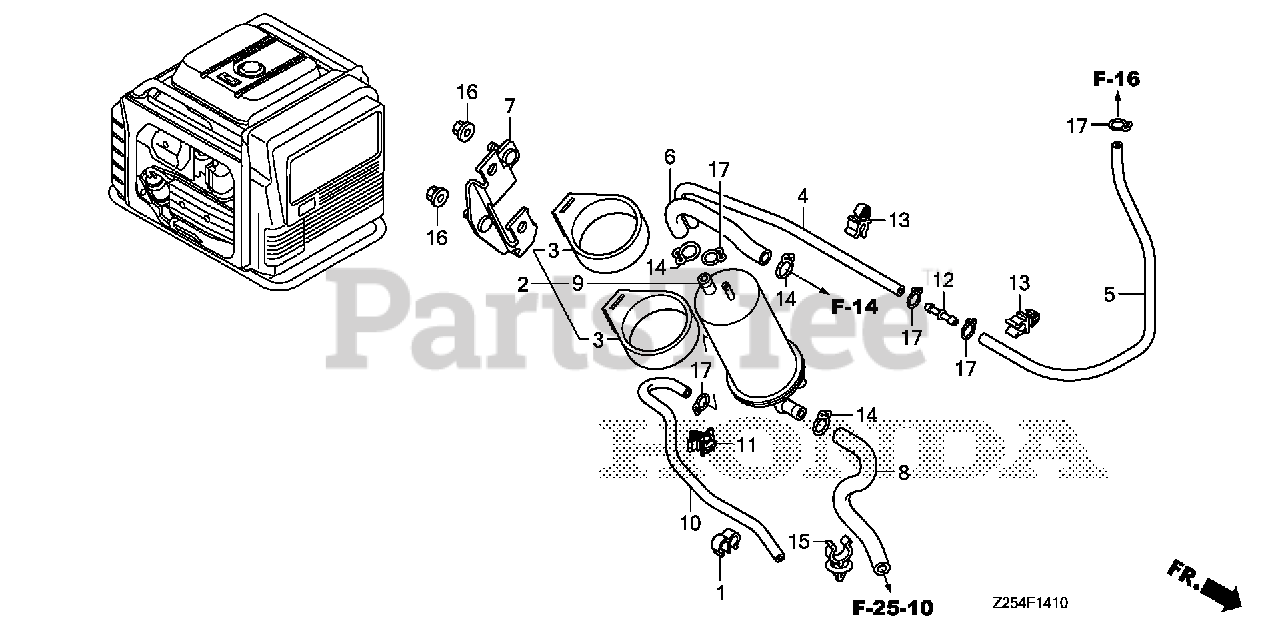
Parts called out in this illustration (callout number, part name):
1	CLAMP, TUBE (7.5X2)
2	CANISTER ASSY.
3	RUBBER, CANISTER MOUNTING
4	TUBE A, CANISTER CHARGE
5	TUBE, CANISTER CHARGE
6	TUBE, CANISTER PURGE
7	STAY, CANISTER
8	TUBE, CANISTER AIR
9	CANISTER ASSY.
10	TUBE, CANISTER DRAIN
11	CLIP, WIRE HARNESS
12	JOINT B, WASHER TUBE (MITSUBA)
13	CLIP, TUBE
14	CLIP, TUBE
15	CLAMP, SUB-TUBE
16	NUT, FLANGE (6MM)
17	CLIP, TUBE (B7)
